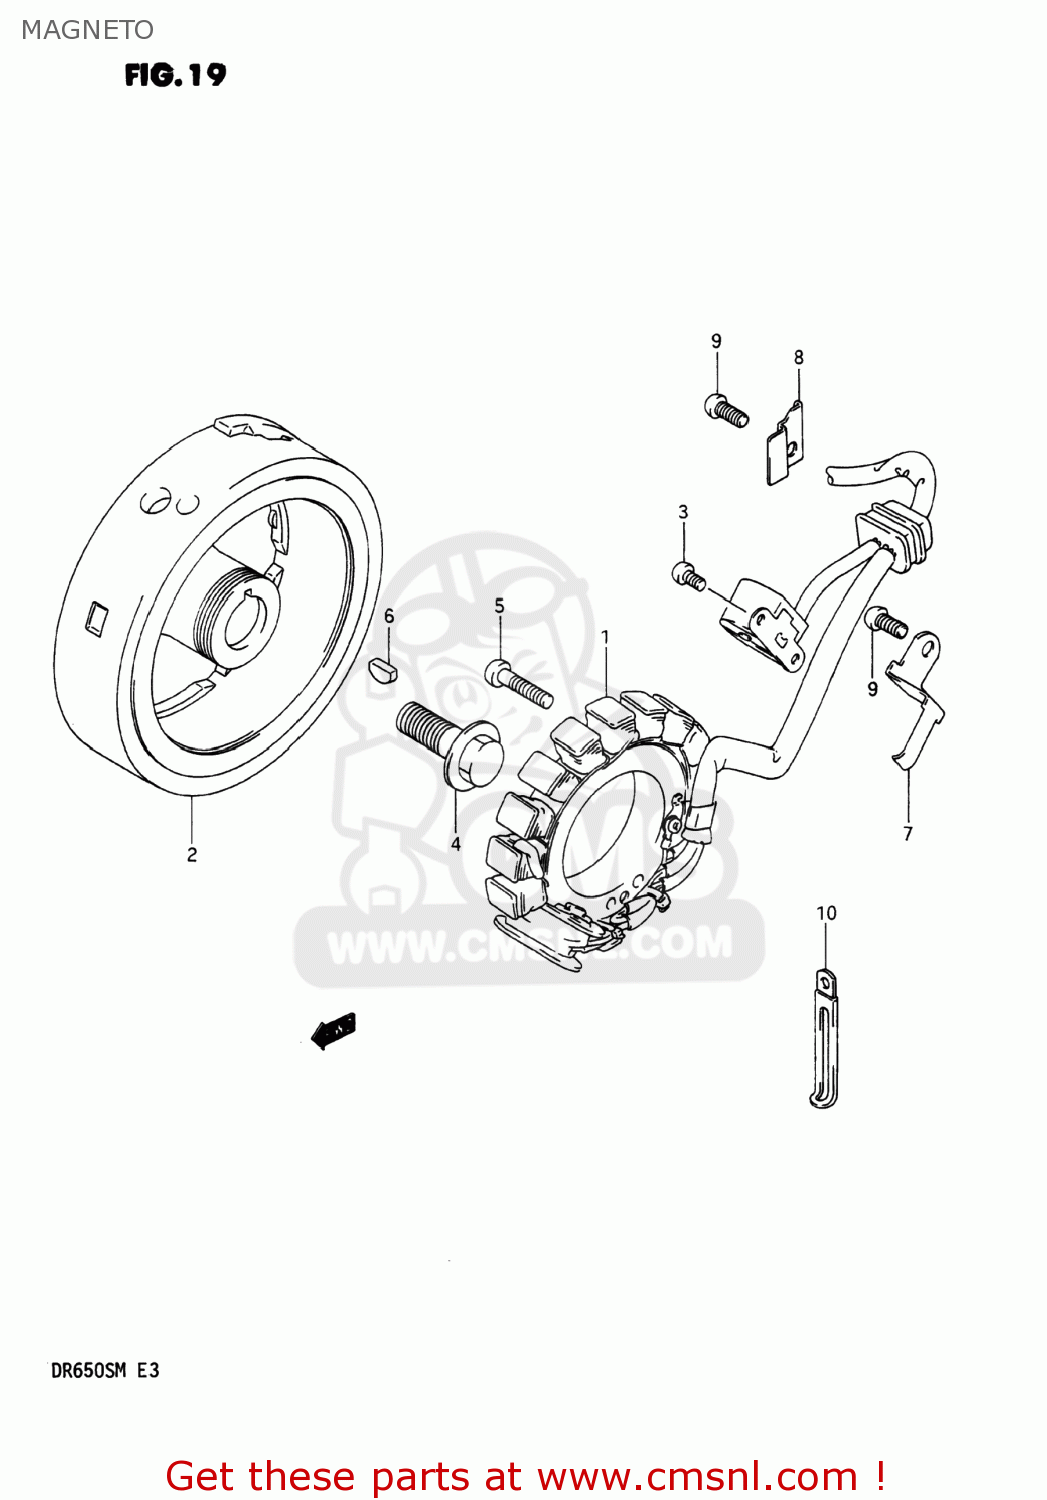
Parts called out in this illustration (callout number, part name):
1	STARTER ASSY
2	ROTOR
3	SCREW
4	BOLT(14X43)
5	SCREW
6	KEY 4MM
7	CLAMP,MAGNETO LEAD WIRE
8	CLAMP,MAGNETO LEAD WIRE
9	SCREW
10	CLAMP
